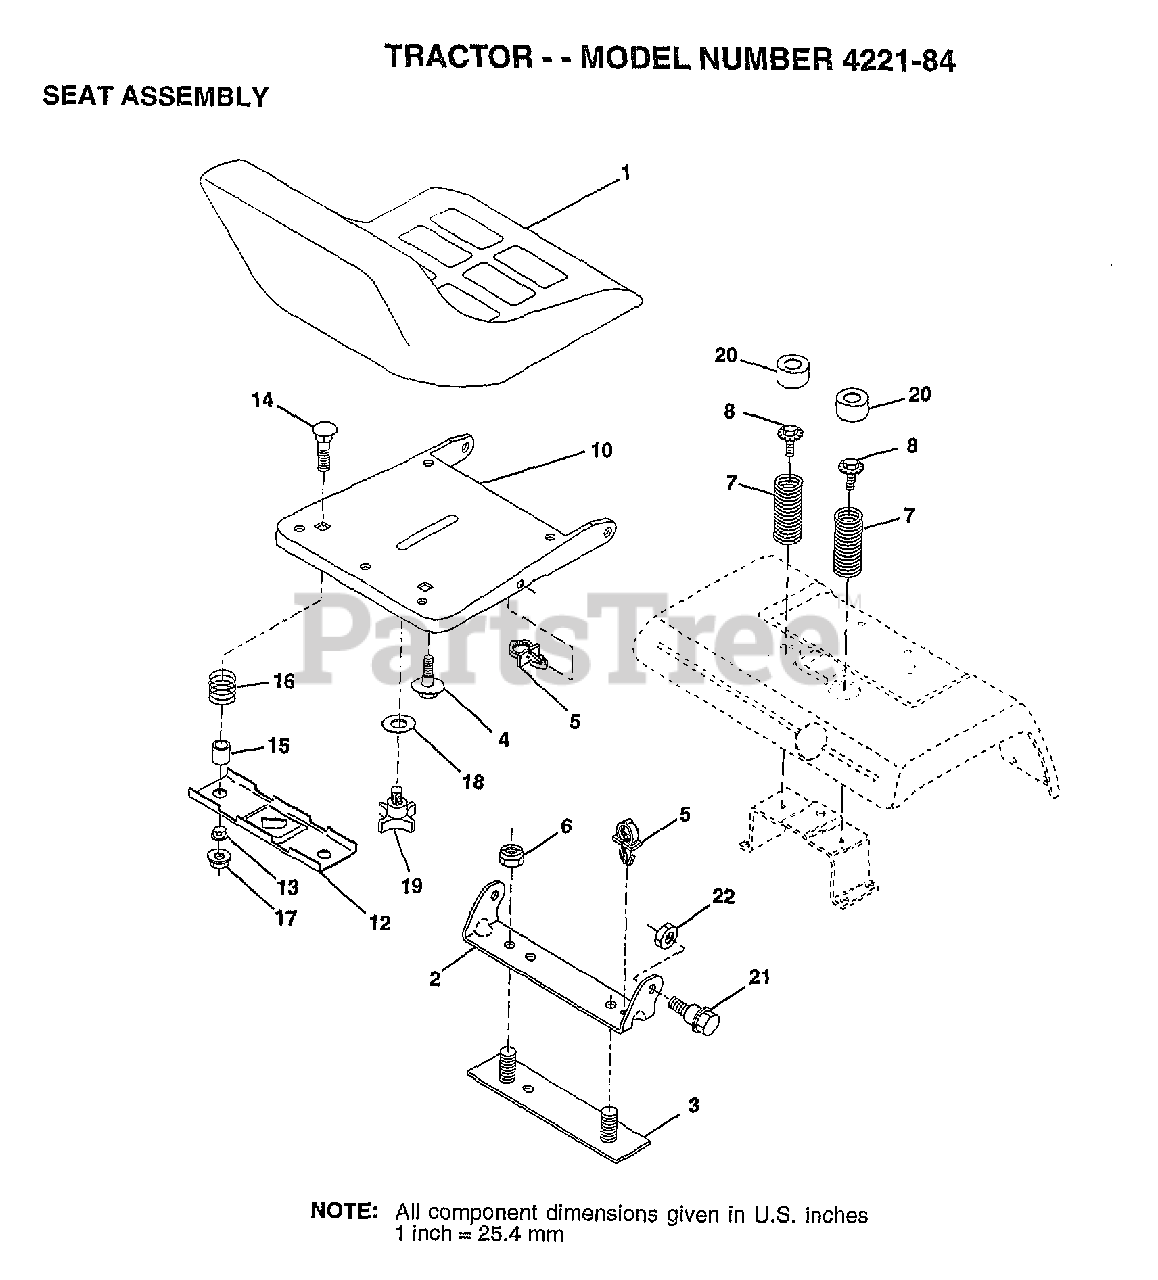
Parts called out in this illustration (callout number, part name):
2	BRACKET PVT SEAT
3	STRAP ASM FENDER
4	"BOLT,SHOULDER"
5	CLIP.PUSH-IN.HING
6	NUT
7	SPRING COMPRESSIO
8	BOLT.5/16-18.UNC
10	PAN-SEAT
12	BRKT SWITCH
13	BUSHING
14	BOLT-RD HD SQ NK
15	SPACER SPLIT
16	SPRING COMPRESSED
18	WASHER
19	"KNOB 1/2"" YT"
20	CAP SPRING
21	"BOLT,SHOULDER"
